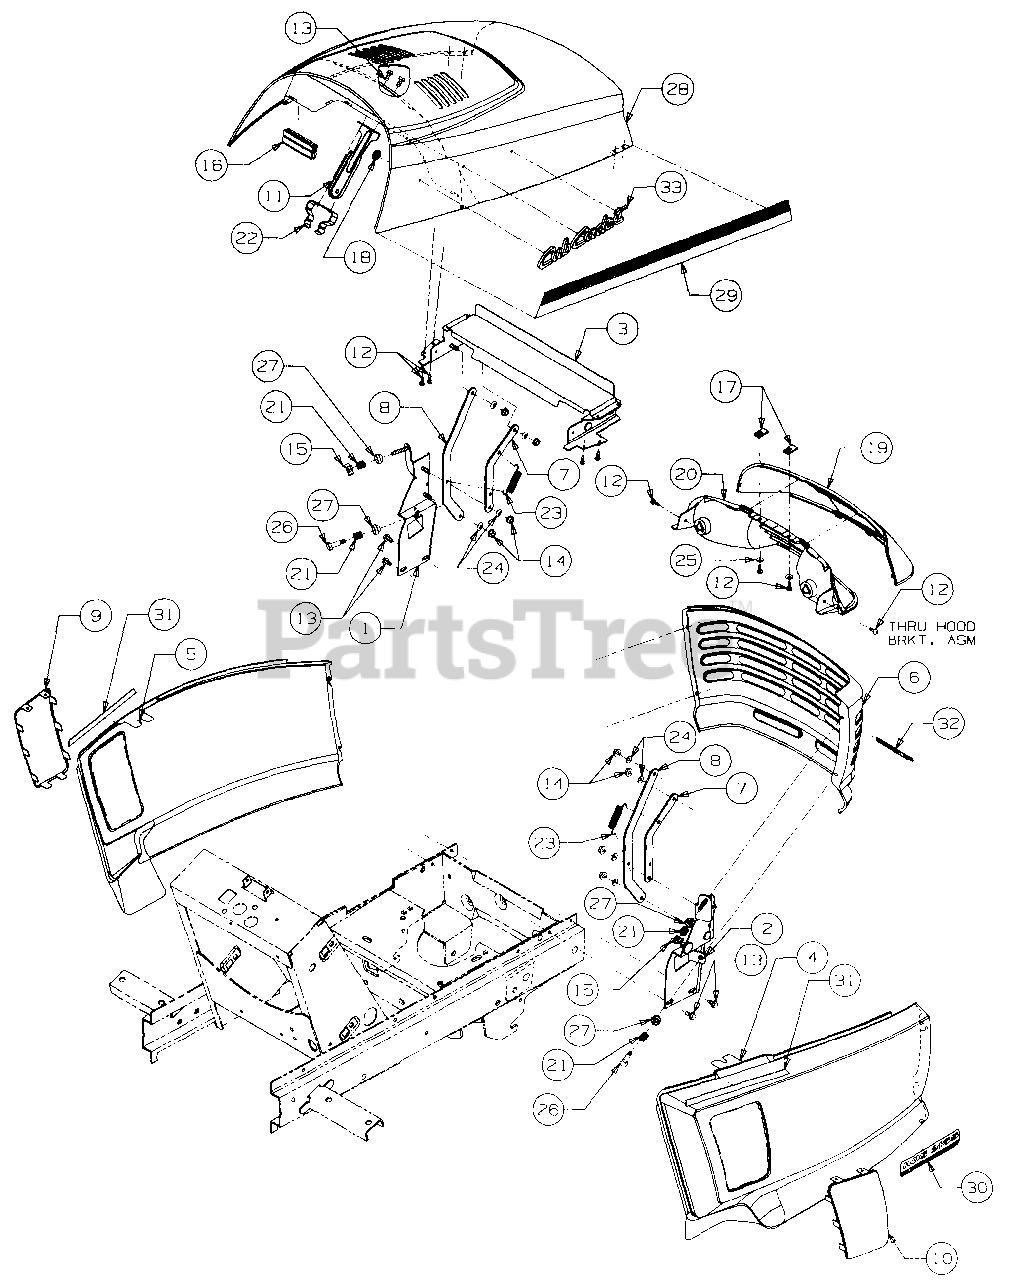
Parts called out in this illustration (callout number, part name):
1	Bracket, Grille LH
2	Bracket, Grille RH
8	Link, Long Hood
12	Screw, Truss Mach Tapp, #10 x .50 Lg
13	Screw, Hex Wash Tapp, 1/4 x .50 Lg
14	Nut, Hex Flange Lock, 1/4-20
15	Nut, Wing, 1/4-20
16	Seal, Heat Baffle
17	Nut, U-Type Speed, #10
18	Retainer, Push Nut
19	Lens, Cub Cadet
20	Reflector, Headlight
21	Spring, Compression, .50 OD x .50 Lg
22	Spring, Hood Latch
23	Spring, Extension, .50 OD x 2.25 Lg
24	Washer, Spring, .265 x .562 x .025 Thk
25	Washer, Flat, .218 x .62 x .063 Thk
26	Bolt, Shoulder, .31 Dia x .75 Lg
27	Bushing, Tapered
30	Graphic, HDS 2165
31	Strip, Protective
32	Graphic, Warning Hot
33	Script w/Studs, Cub Cadet
